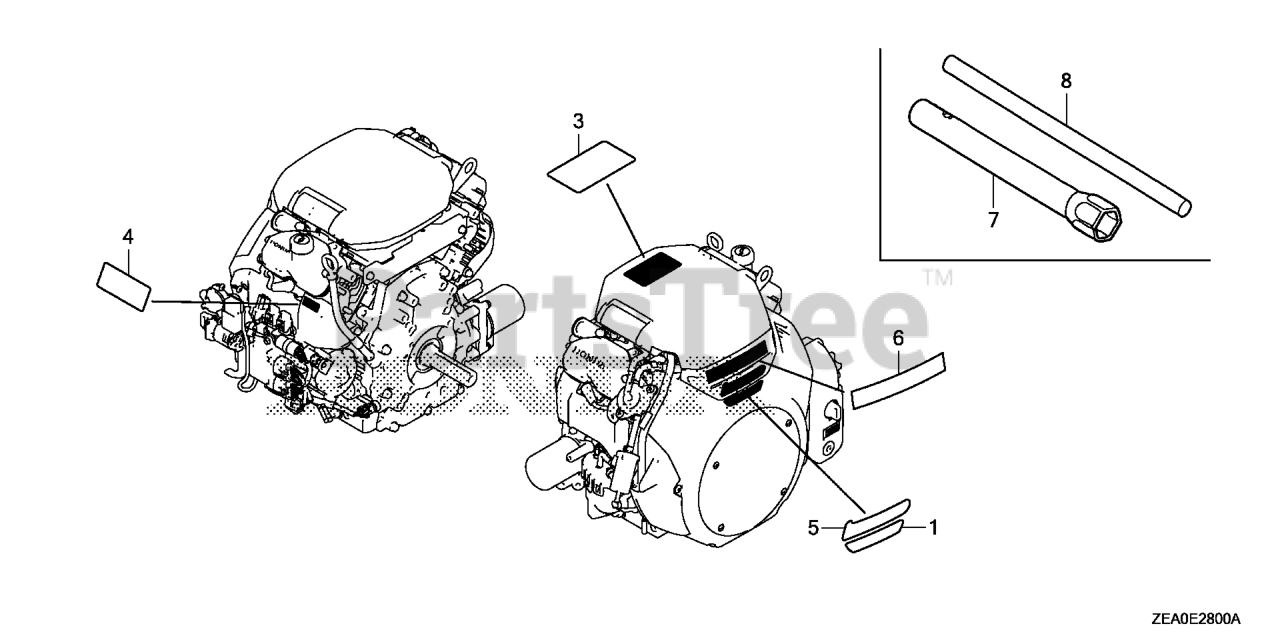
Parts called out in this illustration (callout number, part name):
3	MARK, OPERATOR CAUTION (ENGLISH)(MADE IN CHINA)
4	LABEL, QR CODE (SERVICE)
5	EMBLEM (GX700)
6	MARK, HONDA
7	WRENCH, SPARK PLUG
